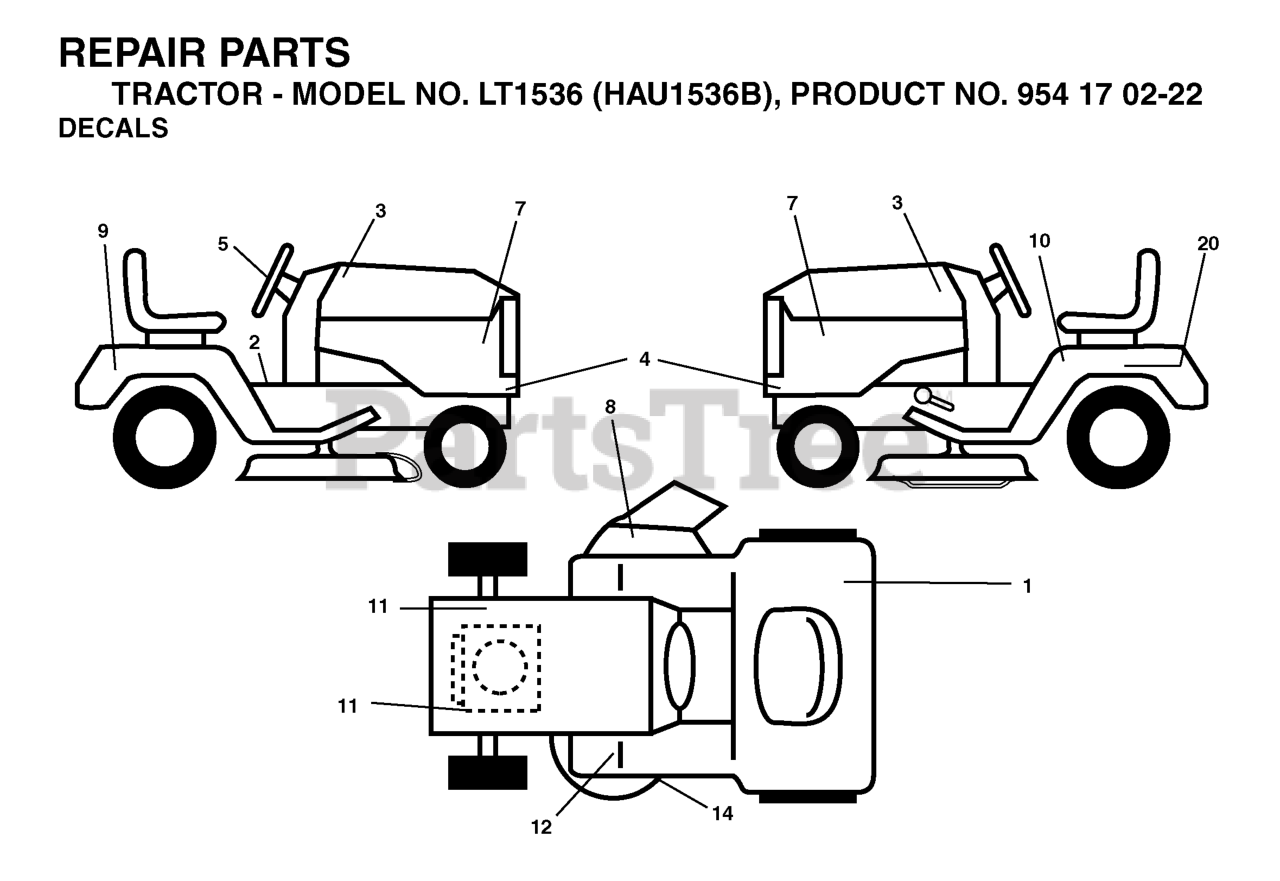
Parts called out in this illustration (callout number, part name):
1	DECAL
2	DECAL PARK BRAKE
5	DECAL.STEERING.HUSQ.BLUE
7	DECAL.HOOD.HUSQVARNA.INTERNATI
8	DECAL.INTERNATIONL.CUTFINGER
10	DECAL READ OWNER'S MAN SYMS
12	DECAL
14	DECAL V-BELT SCHEMATIC
20	DECAL BTRY SYMBOLS
